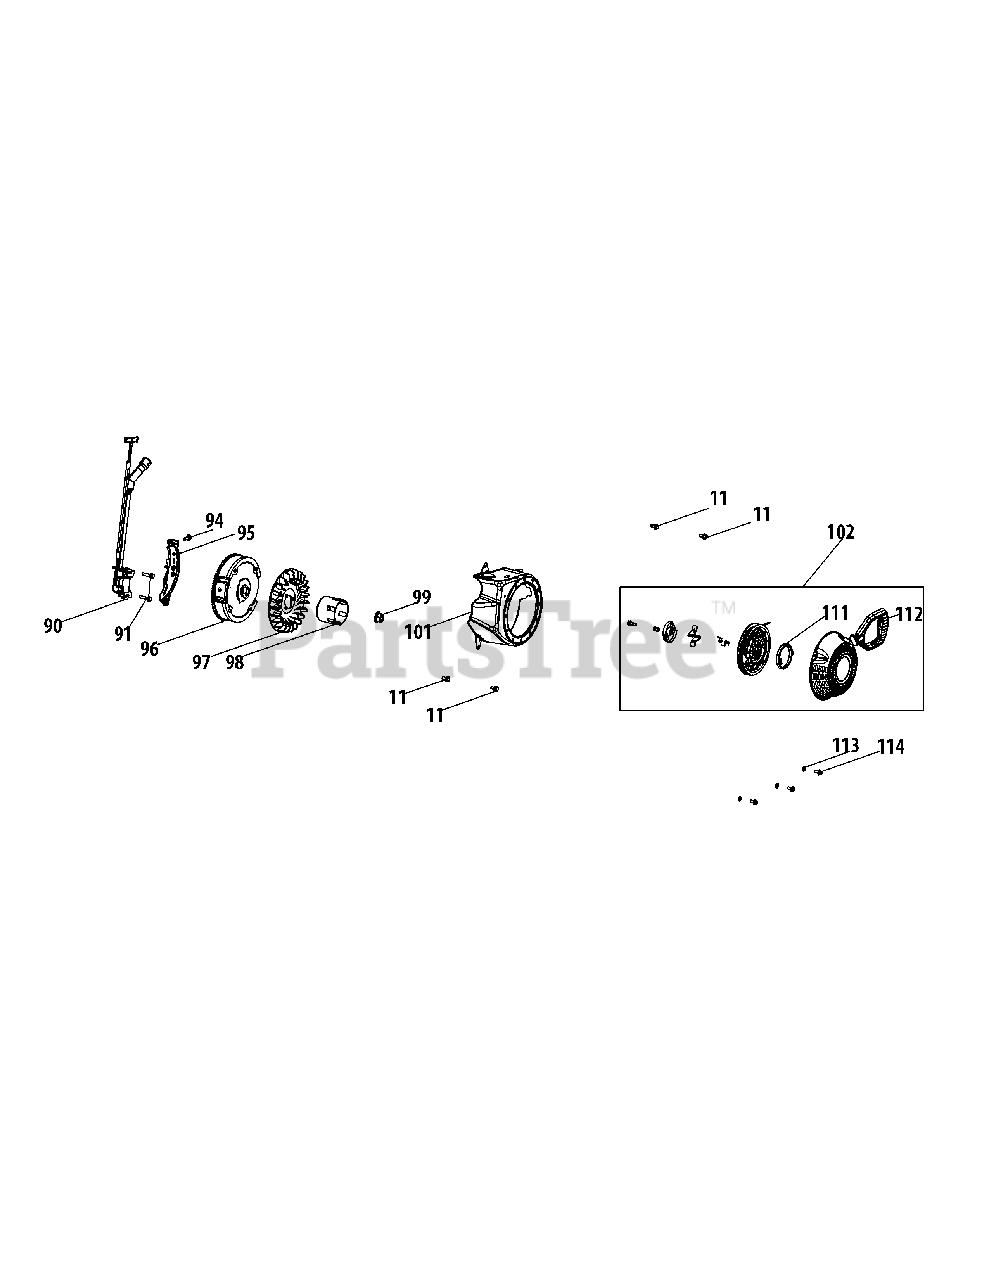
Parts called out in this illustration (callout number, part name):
11	Bolt, M6×12
90	Ignition Module
91	Bolt, M6×25
94	Bolt, M6×20
95	Lower Shield
96	Flywheel
97	Cooling Fan
98	Starter Cup
99	Nut, M14×1.5
101	Blower Housing
102	Recoil Starter
111	Recoil Spring
112	Starter Handle
113	Washer, 6
114	Bolt, M6×12
